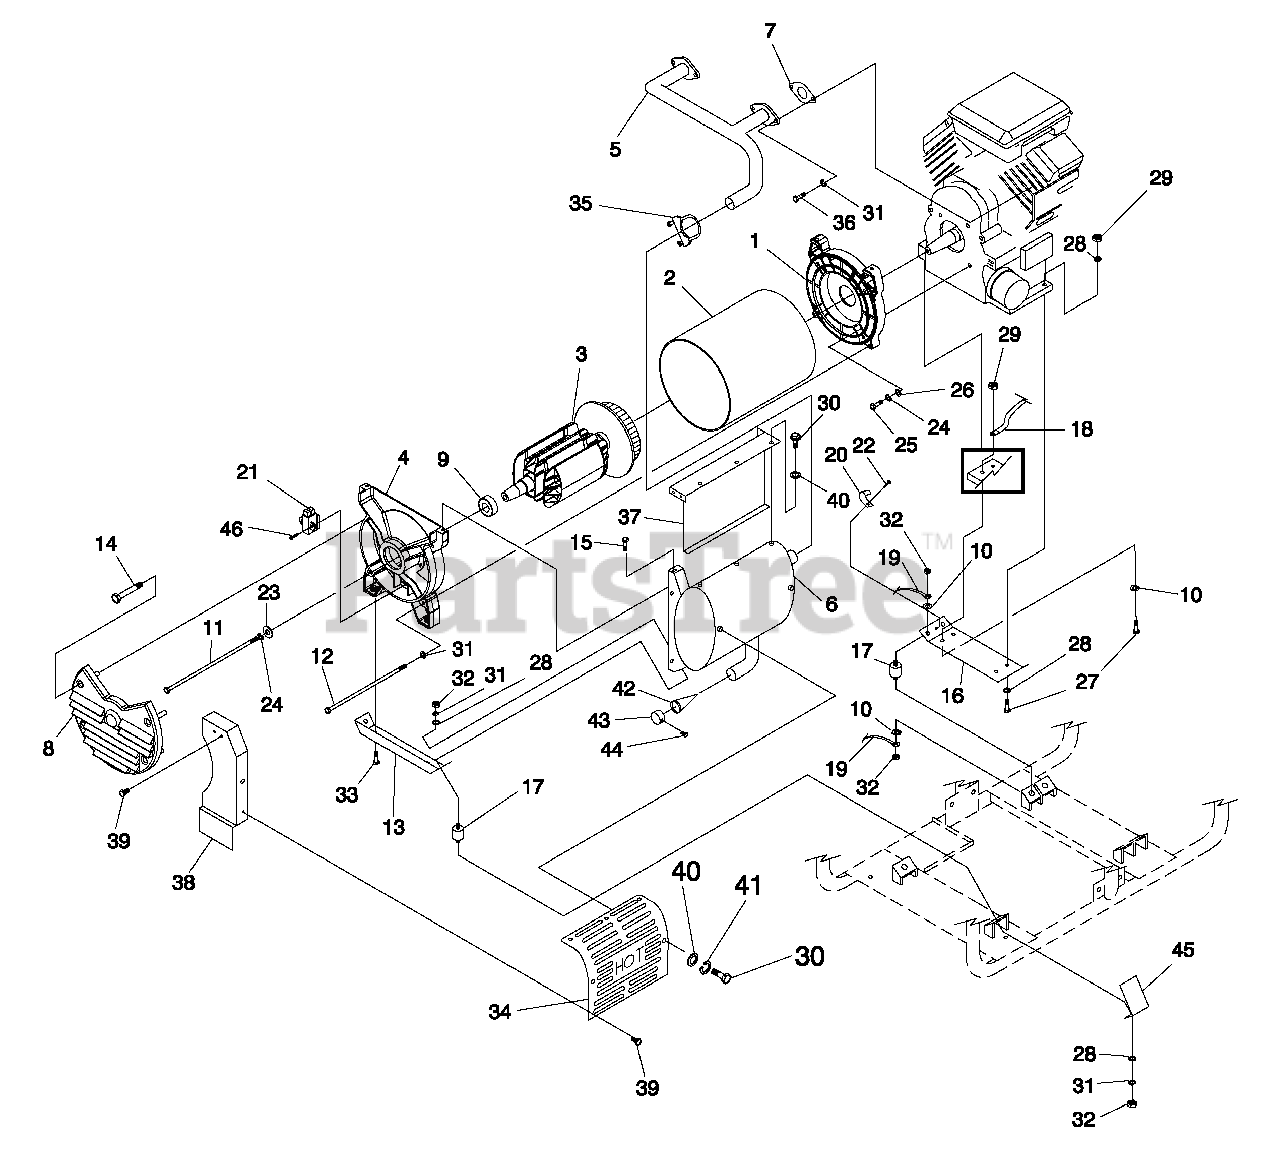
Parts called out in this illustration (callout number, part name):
1	ADAPTOR, ENGINE
2	STATOR 15KW
3	ASSEMBLY, ROTOR WITH FAN 15KW
4	CARRIER, REAR BEARING
5	EXHAUST MANIFOLD
6	MUFFLER
7	GASKET, EXHAUST
8	COVER, ALTERNATOR AIR IN
9	BEARING
10	5/16 SPECIAL LOCK WASHER
11	SCREW IHHC 3/8-24 X 15.50 G5
12	SCREW IHHC M8-1.25 X 400 G8.8
13	BRACKET, ALT MOUNTING
14	SCREW HHTT #10-32 X 1.75
15	SCREW HHTT M8-1.2 X 20
16	ENGINE MOUNTING PLATE
17	RUBBER MOUNT
18	BATTERY CABLE, BLACK
19	EARTH STRAP 3/8X 3/8
20	CLIP-J VINYL COAT .625 ID
21	ASSEMBLY, BRUSH HOLDER
22	SCREW TAP-R #10-32 X 9/16
23	WASHER FLAT 3/8 ZINC
24	WASHER LOCK 3/8
25	SCREW HHC 3/8-16 X 1-1/4 G5
26	WASHER FLAT 3/8-M10 ZINC
27	SCREW HHC M8-1.25 X 50 G8.8
28	WASHER FLAT 5/16 ZINC
29	NUT LOCK HEX M8-1.25 NYLON INSERT
30	SCREW HHC M6-1.0 X 12
31	WASHER LOCK M8-5/16
32	NUT HEX 5/16-18 STEEL
33	SCREW TAPTITE 3/8-16 X 3/4 BP
34	SHIELD, MUFFLER HEAT
35	U-BOLT & SADDLE
36	SCREW SHC M8-1.25 X 18
37	PANEL, MUFFLER BOX BACK
38	PANEL, MUFFLER BOX END
39	SCREW HHTT M6-1.0 X 12
40	WASHER FLAT M6-1/4
41	WASHER LOCK M6-1/4
42	SPARK ARRESTOR SCREEN
43	RETAINER, SPARK ARREST SCREEN
44	SCREW HHTT M4-0.7 X 8
45	SHIELD, RUBBER MOUNT
46	SCREW HHTT M5-0.8 X 16
